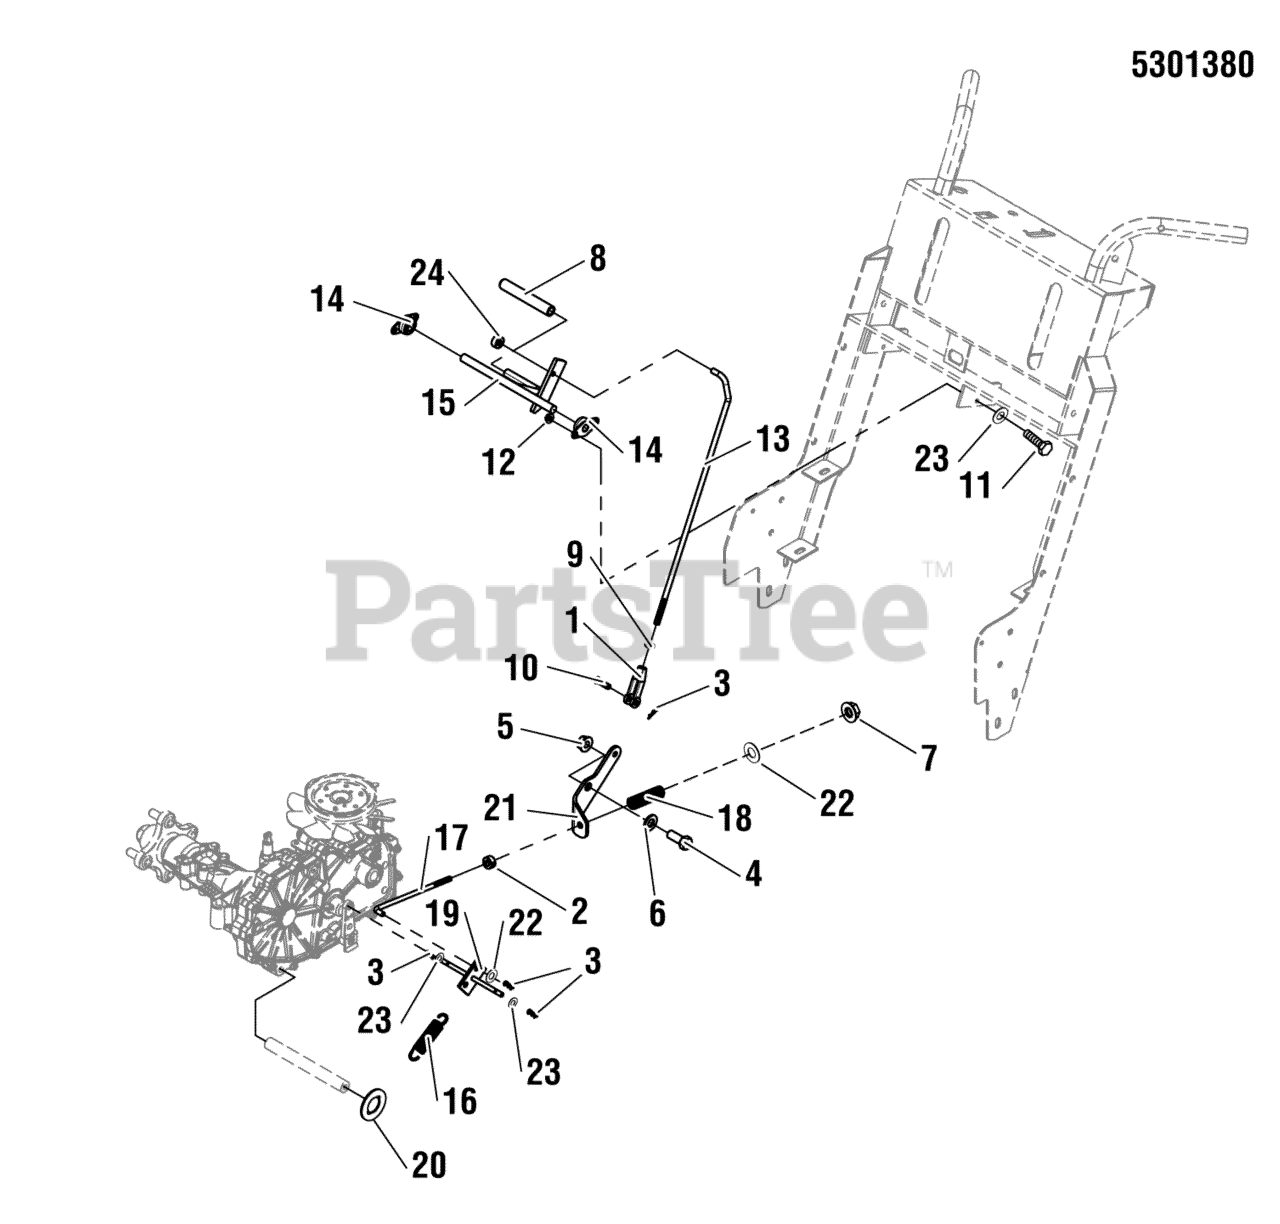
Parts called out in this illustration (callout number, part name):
1	CLEVIS, 5/16-24, STEEL, CLEAR ZINC
2	COLLAR, DOUBLE SPLIT, 5/16 CZ
3	PIN, HAIR, .0585 X 1-1/8, 1/4 EYE, YZ
4	BOLT, 1/2-13 X 1-1/2 GD5 CZ
5	NUT, Hex Flange, Nylock, 1/2-13
6	WASHER, 1/2 SAE
7	NUT, 5/16-24 HEX NYLON LOCK
8	GRIP, FOAM
9	NUT, 5/16-24 JAM
10	PIN, CLEVIS, 5/16 X 1 YZ
11	BOLT, 1/4-20 X 3/4 GD5 YZ
12	NUT, 1/4-20 HEX NYLOCK FLANGE
13	ROD, PULLER ROD
14	BEARING, 1/2" FLANGED
15	WELD BRAKE SHAFT - RED
16	SPRING-EXT, .75 OD X 3.40 LG, X .115 WR
17	ROD, LOWER BRAKE CONTROL
18	SPRING, CONTROL ROD
19	WELD, BRAKE LINK CONNECTOR - RED
20	WASHER, KEYED, 1-1/2 OD
21	LINK, BRAKE PIVOT
22	WASHER, 5/16" SAE
23	WASHER, 1/4 SAE
24	COLLAR, 5/16 SET
